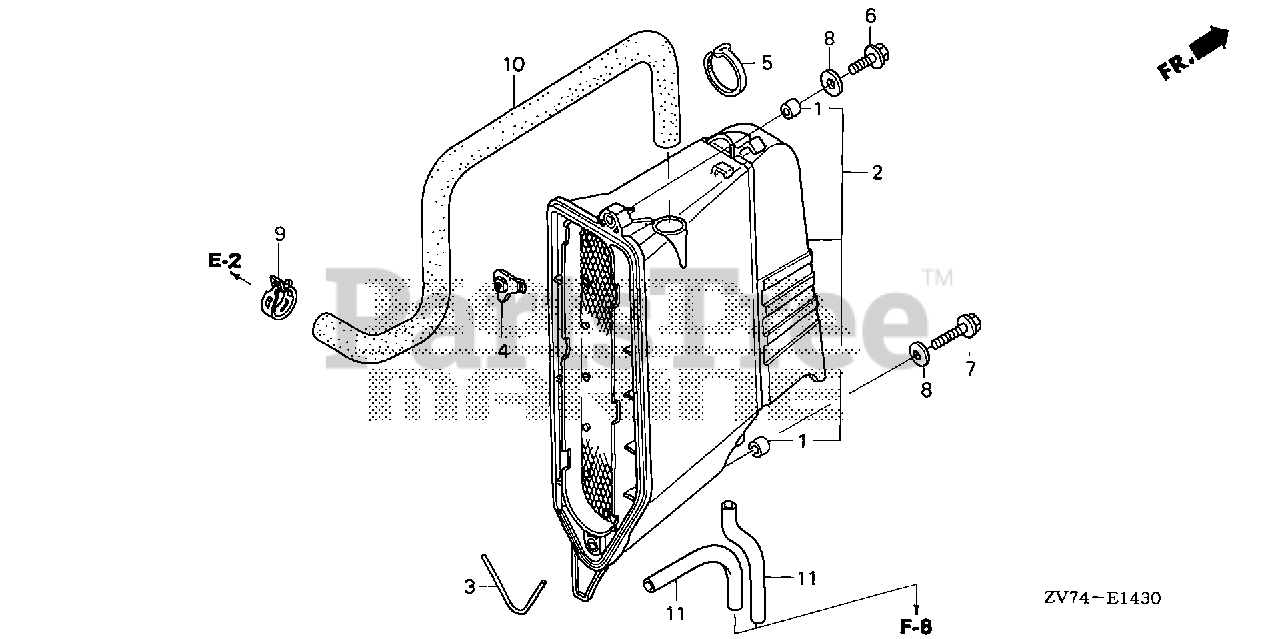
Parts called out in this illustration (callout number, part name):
1	COLLAR, DISTANCE
2	COVER, MUFFLER
3	GASKET, MUFFLER COVER
4	NUT, MUFFLER COVER
6	BOLT, FLANGE (6X25)
7	BOLT, FLANGE (6X40)
8	WASHER (6.5X18)
9	CLAMP, TUBE (D17)
10	TUBE, BREATHER
11	BULK HOSE, VINYL (4.5X8X1000) (4.5X8X70)
